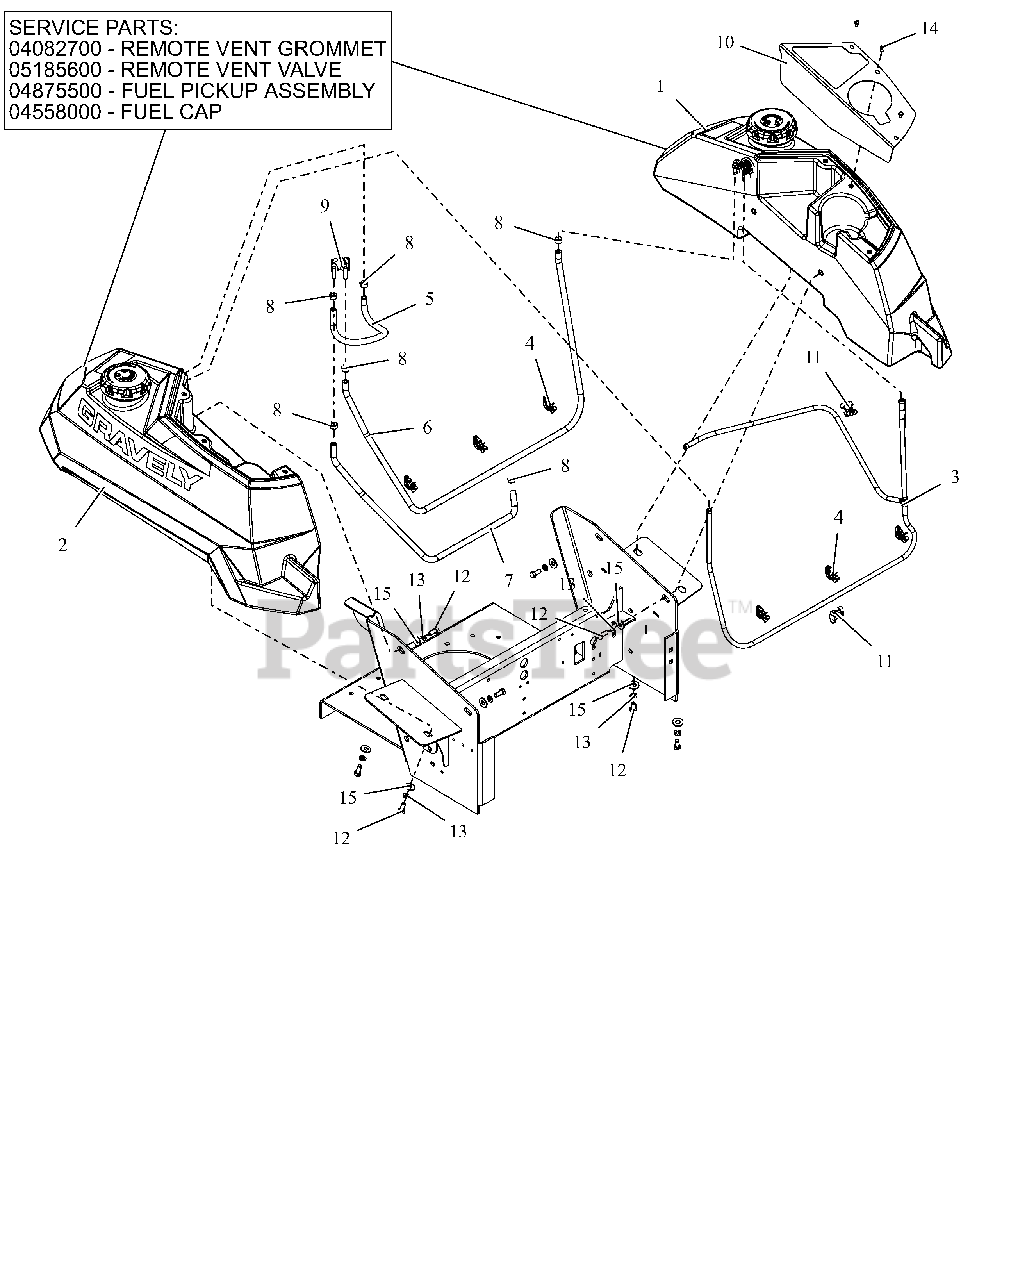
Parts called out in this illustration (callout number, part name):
1	ASM, LH - PT FUEL TANK
2	ASM, RH - PT FUEL TANK
2	GROMMET, REMOTE VENT NITRILE
2	VALVE, COMBINATION VENT 3/16
2	ASSM,LRG TANK FUEL PICKUP LINE
2	CAP, FUEL VENTIN AUTOLOCK
3	ASM, VAPOR LINE
4	WIRE CLIP
5	HOSE, .25 LOW-PERM BULK GAS
6	HOSE, .25 LOW-PERM BULK GAS
7	HOSE, .25 LOW-PERM BULK GAS
8	CLAMP, FUEL LINE
9	VALVE, FUEL
10	PT CUPHOLDER PANEL - RED
11	CLIP, T, .38-.50
12	@BLT-HEX .31-18X.75 GR5 YWZC
13	@WSHR-LK .31X.078 REG YWZC
14	SCR-MCH 10-24X.38 HWHSTAINLESS
15	@WSHR-FL-STL.38X.875X.083 YWZC
